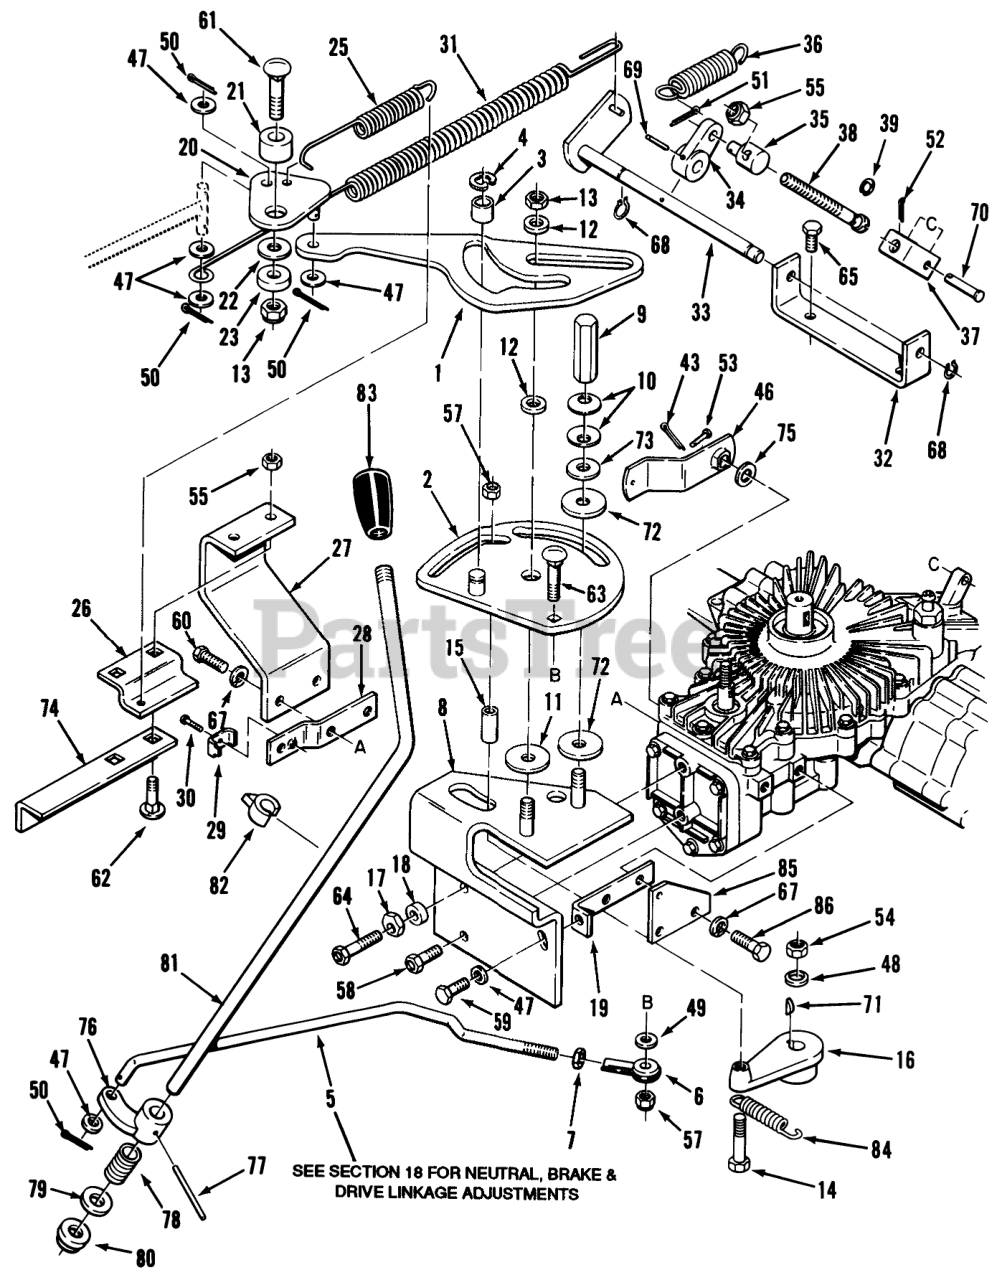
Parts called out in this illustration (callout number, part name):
1	NEUT-RETURN PLATE
2	ASS'Y-CAM PLATE
3	BEARING-CAM RETURN
4	E Ring
5	ROD-SPEED CONTROL
6	ASSY ROD END
7	Jam Nut 1/4-28
8	ASS'Y-CAM PLATE S R
9	NUT-SPECIAL 3/8 X 2"
10	WASHER-SPRING DISC
11	FRICTION WASHER
12	CAM-SPACER
13	NUT-HEX, JAM
14	HHMS 1/4-20 X 2 1/2
15	SPACER
16	ARM MOTION CONTROL
18	SPACER-GEAR
19	ASS'Y-ANGLE SUPPORT
20	PIVOT PLATE ASSY R
21	SPACER
22	WASHER-SPECIAL
23	SPACER-LIFT LINK
25	SPRING-RETURN
26	BRACKET R
27	BRACKET-TORQUE R
28	PLATE-MOUNTING R
29	CLAMP THROTTLE
30	HWHTRS 10-24 X 1/2
31	SPRING-BRAKE
32	BRACKET
33	ASS'Y-BRAKE PIVOT
34	PLATE
35	TRUNNION-CLUTCH ROD
36	SPRING-BRAKE
37	CLEVIS R
38	BOLT-ADJUSTING
39	E-Ring
43	Cotter Pin
46	Plate
47	WASHER 5/16 SAE
48	Washer
50	Cotter Pin
51	Cotter Pin
52	Cotter Pin
54	Nut
55	Nut
57	Nut
58	Screw
59	Bolt
60	Bolt
61	Bolt
62	Bolt-Carriage
63	Carriage Bolt 1/4-20 x 1
64	Bolt
65	Bolt
67	Lockwasher
68	EXTERNAL SNAP RING
69	Pin-Roll
71	KEY WOODR 1/8X1/2 DI
72	WASHER-FRICTION
73	Washer
74	BRACKET R
75	Washer
76	ARM SHIFTER B
77	SPIROL PIN 7/32X21/2
78	SPRING COMPRESSION
79	Washer
80	BUSHING-NYLINER
81	ROD-SHIFT LEVER
82	POINTER
84	SPRING
85	BRACKET-SPRING
86	Bolt
